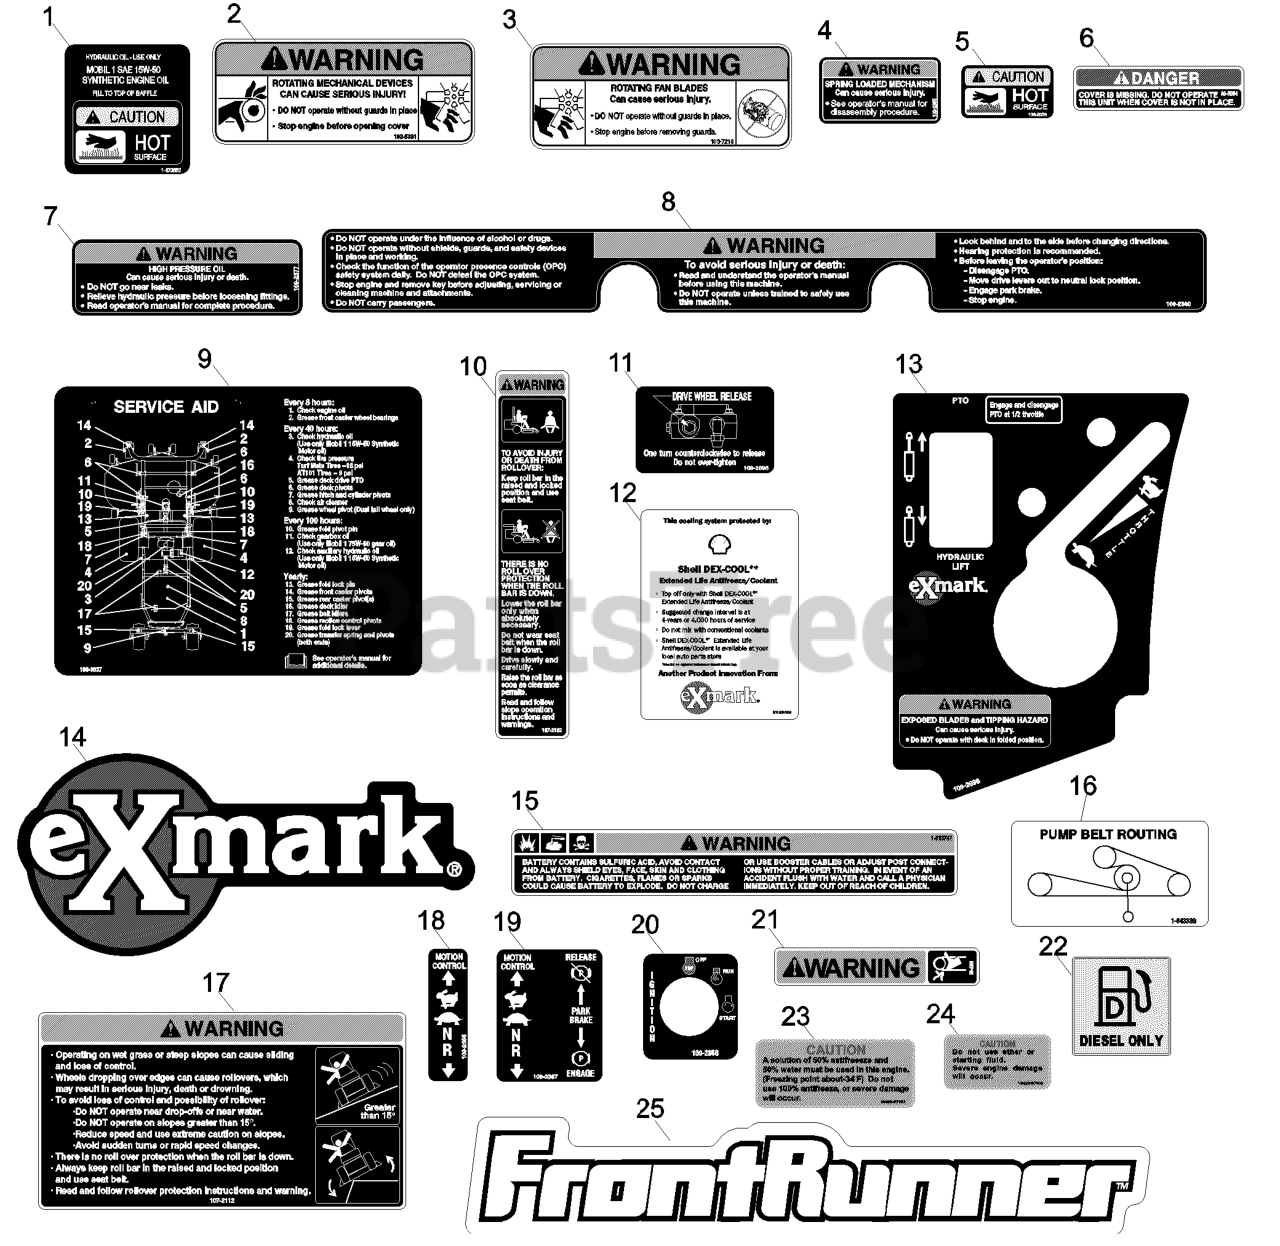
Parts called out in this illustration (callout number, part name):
2	DECAL-DEVICES, ROTATING
3	DECAL,PUMP FAN WARNING
4	DECAL,SPRING LOADED
5	DECAL-CAUTION
6	DECAL-COVER, MISSING
7	DECAL,HIGH PRESSURE OIL
8	DECAL,TOP CONSOLE
9	DECAL,FR SERVICE AID
10	DECAL-WARNING, FOLDING RO
11	DECAL,PUMP DRIVE RELEASE
12	DECAL,SHELL COOLANT
13	DECAL,CONSOLE FMZ DIESEL
14	DECAL,EXMARK LOGO
15	DECAL-BATTERY
16	DECAL-ROUTING, BELT
17	DECAL-WARNING
18	DECAL-CONTROL, MOTION
19	DECAL,MOTION CNTL/PARK BR
20	DECAL,IGNITION
21	DECAL-WARNING
22	DECAL-FUEL
23	DECAL-ANTIFREEZE
24	DECAL-CAUTION
25	DECAL,FRONTRUNNER
